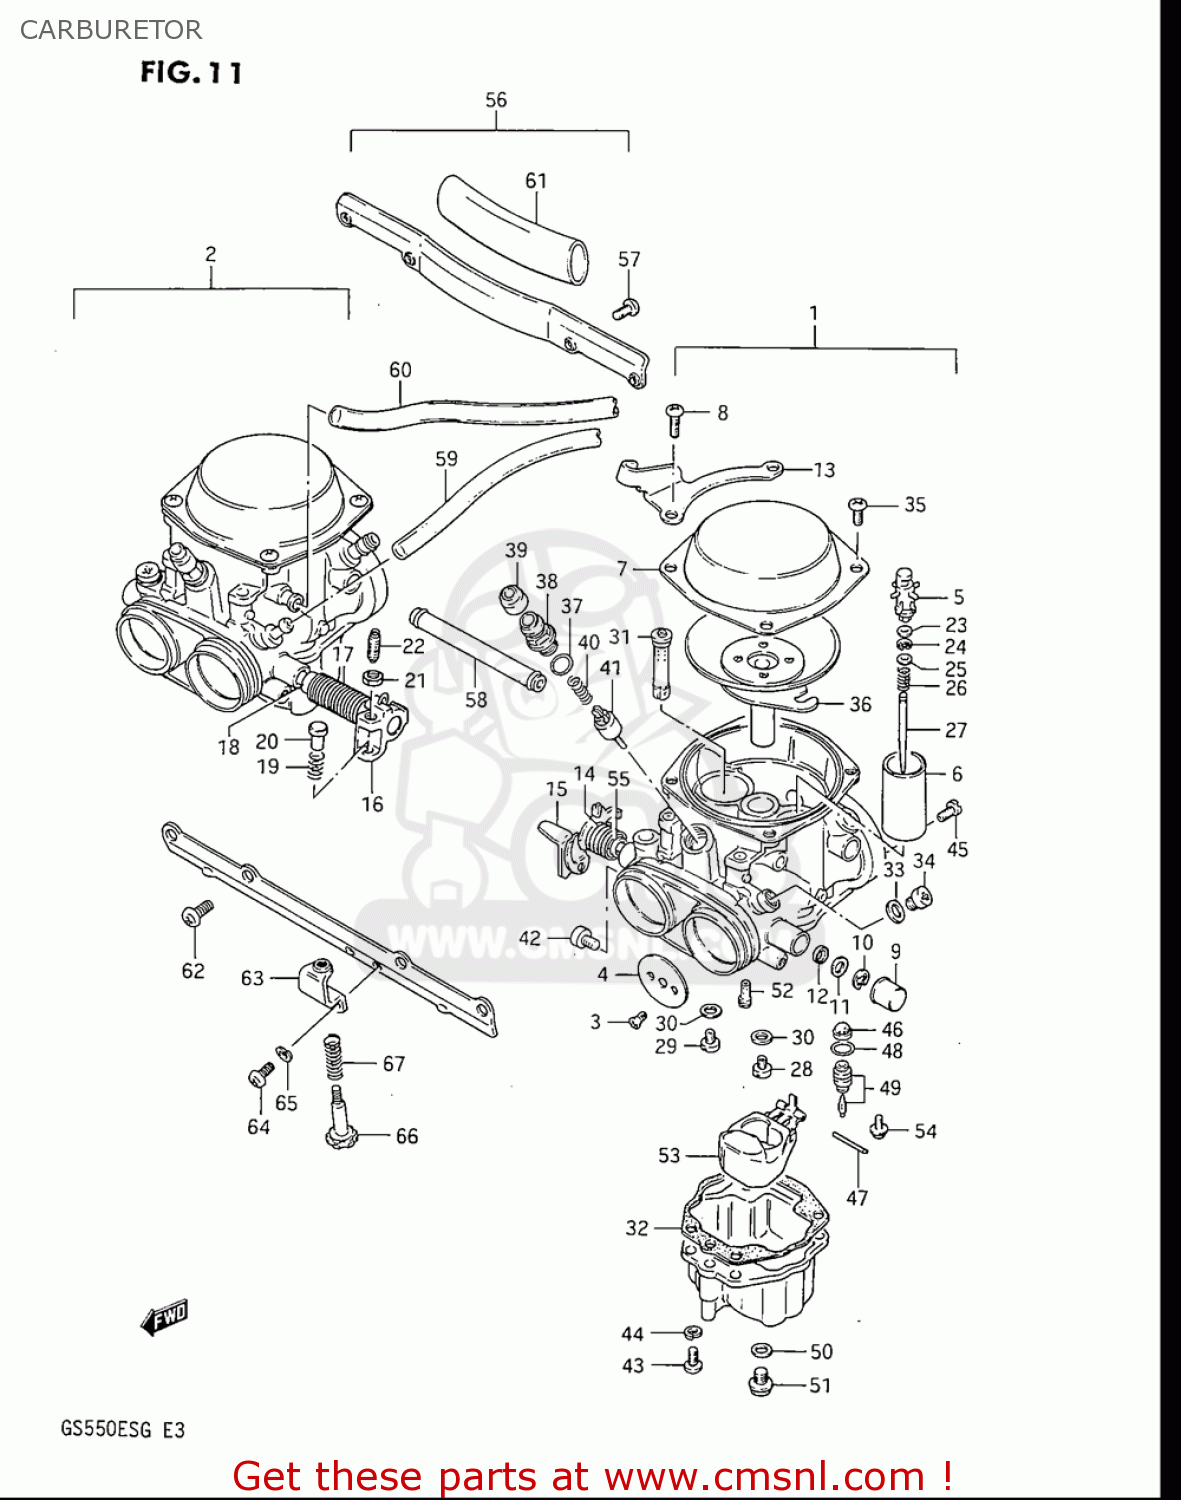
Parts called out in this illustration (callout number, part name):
3	SCREW
5	HOLDER,GUIDE
8	SCREW
9	CAP
10	E RING
11	GASKET,THROTTLE SHAFT (NAS)
12	SEAL
14	SPRING,THROTTLE SHAFT
17	SPRING
19	SPRING,THROTTLE SCREW
20	PIN,THROTTLE LEVER
21	NUT
22	SCREW
23	RING
24	CLIP
25	WASHER
26	SPRING
28	JET,MAIN(95)
29	JET,MAIN
30	WASHER
32	GASKET (NAS)
33	WASHER
34	SCREW
35	SCREW
36	DIAPHRAGM,CARBURETOR
37	O RING
38	HOLDER,GUIDE
39	CAP
40	SPRING
41	VALVE,STARTER
42	SCREW
43	SCREW 4X16
44	WASHER,LOCK
45	JET,PILOT(150)
46	FILTER
47	PIN,FLOAT
48	O RING,NEEDLE VALVE SEAT
49	VALVE ASSY,NEEDLE
50	GASKET (NAS)
51	PLUG,DRAIN
52	JET,PILOT(37.5)
53	FLOAT
54	SCREW
55	RING,THROTTLE SHAFT
57	SCREW
58	PIPE,CARBURETOR
59	HOSE(4.5X8.5X600)
60	HOSE(7X11X600)
61	HOSE(16X19X100)
62	SCREW
64	SCREW
65	LOCK,WASHER
66	ADJUSTER
67	SPRING
